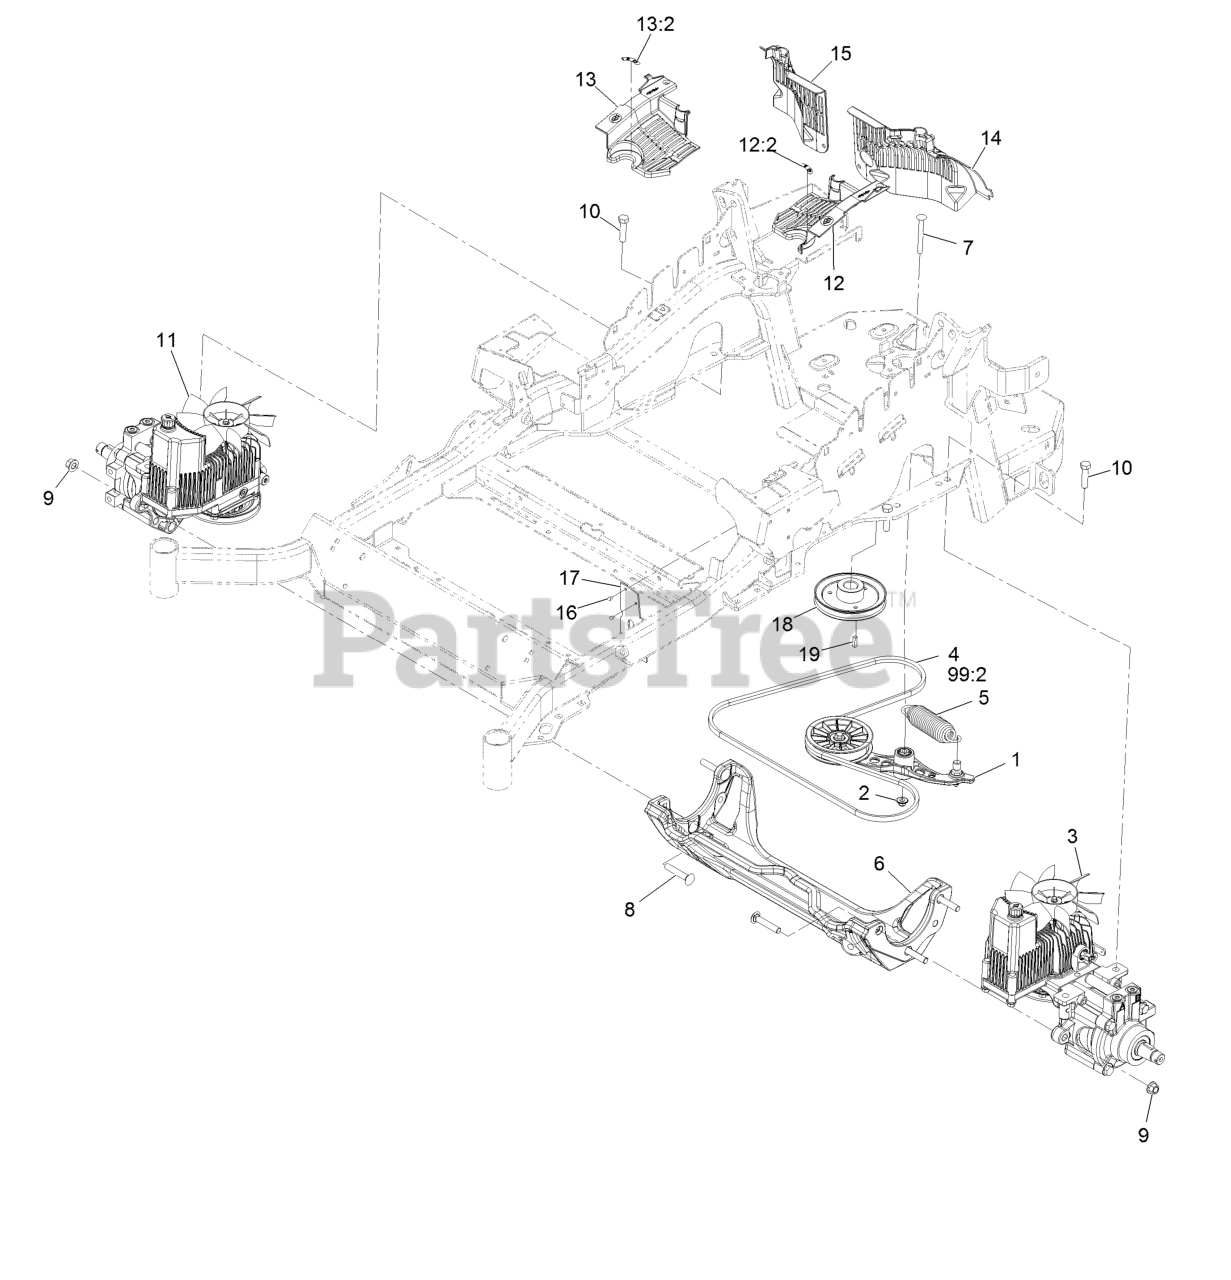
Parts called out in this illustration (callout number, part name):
1	Pump Idler ASM
2	Nut-Nyloc 3/8-16 Flg
3	LH Hydro ASM (12Cc W/ Shock)
4	Belt
5	Spring-Extension
6	Cradle-Hydro
7	Bolt-Carriage Shoulder 3/8-16 X 3 1/2
8	Screw-CARR
9	Nut-Lock 1/2-13
10	Screw-HH 1/2-13 X 1 1/4
11	RH Hydro ASM (12Cc W/ (Shock)
12	LH Hydro Guard ASM
12:2	Decal-Oil, Hydro
13	RH Hydro Guard ASM
13:2	Decal-Oil, Hydro
14	Guard-Hydro, Rear (LH)
15	Guard-Hydro, Rear (RH)
16	Rivet 3/16 X 1/4
17	Deflector-Air Flow
18	Sheave
19	Key-Machine 1/4 X 1/4 X 1
99	Bottle-Oil, 32Oz Hydraulic
99	Filter-Hydro
99	Bottle,Oil 1 Gallon Hydraulic
99	Kit, Hydro Service
99:1	Bottle-Oil, 32Oz Hydraulic
99:2	Belt
99:3	Filter-Hydro
